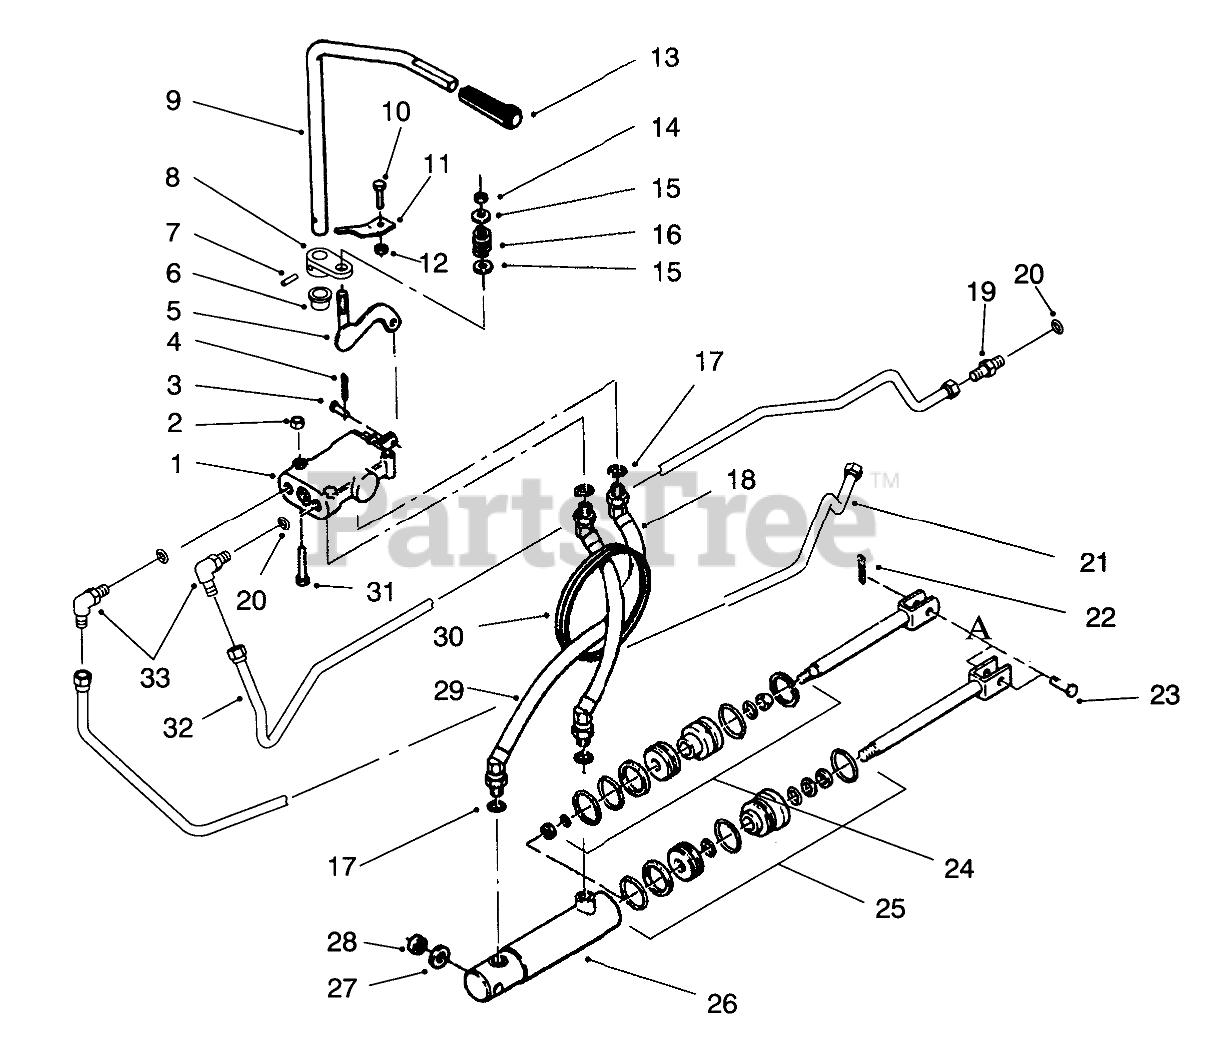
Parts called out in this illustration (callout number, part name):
1	Valve-Hydraulic (Incl. Ref.#3-4)
2	NUT-LOCK, NI
3	Pin
4	PIN-COTTER
5	WLDMT-LIFT BAR
6	NYLINER BUSHING
7	SPIROL PIN 7/32X7/8
8	ARM-CONTROL
9	ROD-LIFT CONTROL
10	SCREW-HH
11	BRACKET-CONTROL R B
12	NUT-LOCK, NI
13	KNOB-HYDRAULIC LIFT
14	NUT-LOCK, NI
15	WASHER-PLAIN
16	SPRING
17	O RING
18	Hose ASM-Hydraulic
19	Fitting-Straight Adapter (Incl. Ref. #20)
20	0-Ring
21	TUBE-HYD PRESSURE
22	PIN-COTTER
23	Pin-Clevis
24	S/A O-RING&GASKET AS
25	S/A 108872 HYD CYL
26	Cylinder-Hydraulic (Incl. Ref.#24-25)
27	Washer
28	SPACER-OUTER
29	Hose ASM-Hydraulic
30	GROMMET
31	SCREW-HH
32	TUBE-HYD RETURN
33	Fitting-90deg. (Incl. Ref. #20)
